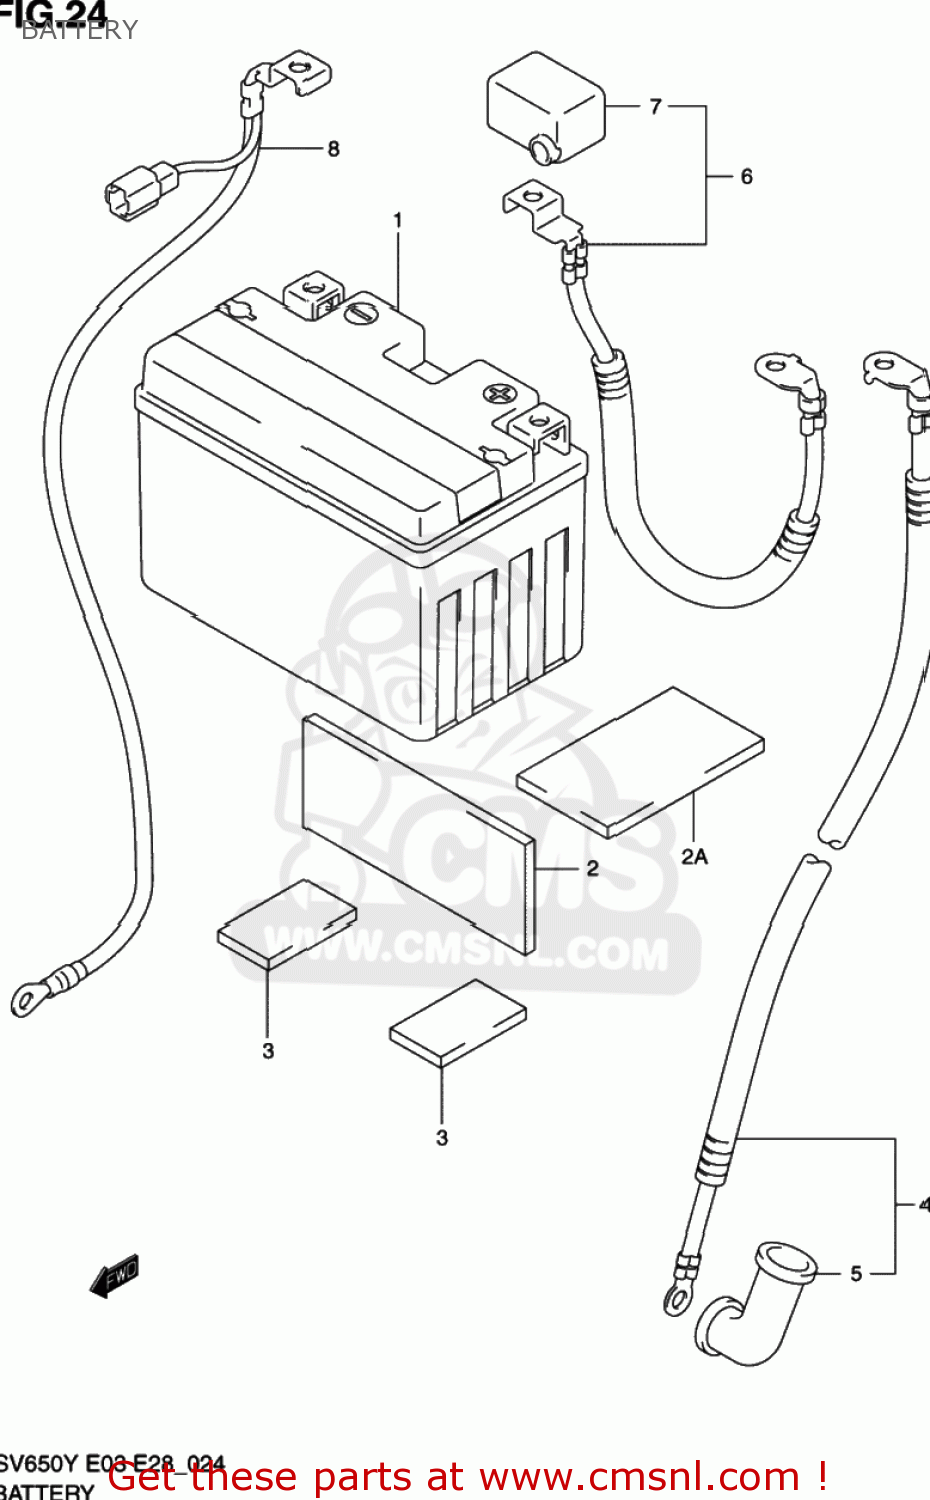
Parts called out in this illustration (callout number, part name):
1	BATTERY ASSEMBLY (12V) YT1
2	PROTECTOR(170X95X3.0)
2A	PROTECTOR(40X85X5)
3	CUSHION 20X45X6
4	WIRE,STARTER MOTOR LEAD
5	CAP,STARTER MOTOR LEAD
6	WIRE,BATTERY PLUS LEAD
7	CAP,BATTERY PLUS
8	WIRE,BATTERY M
